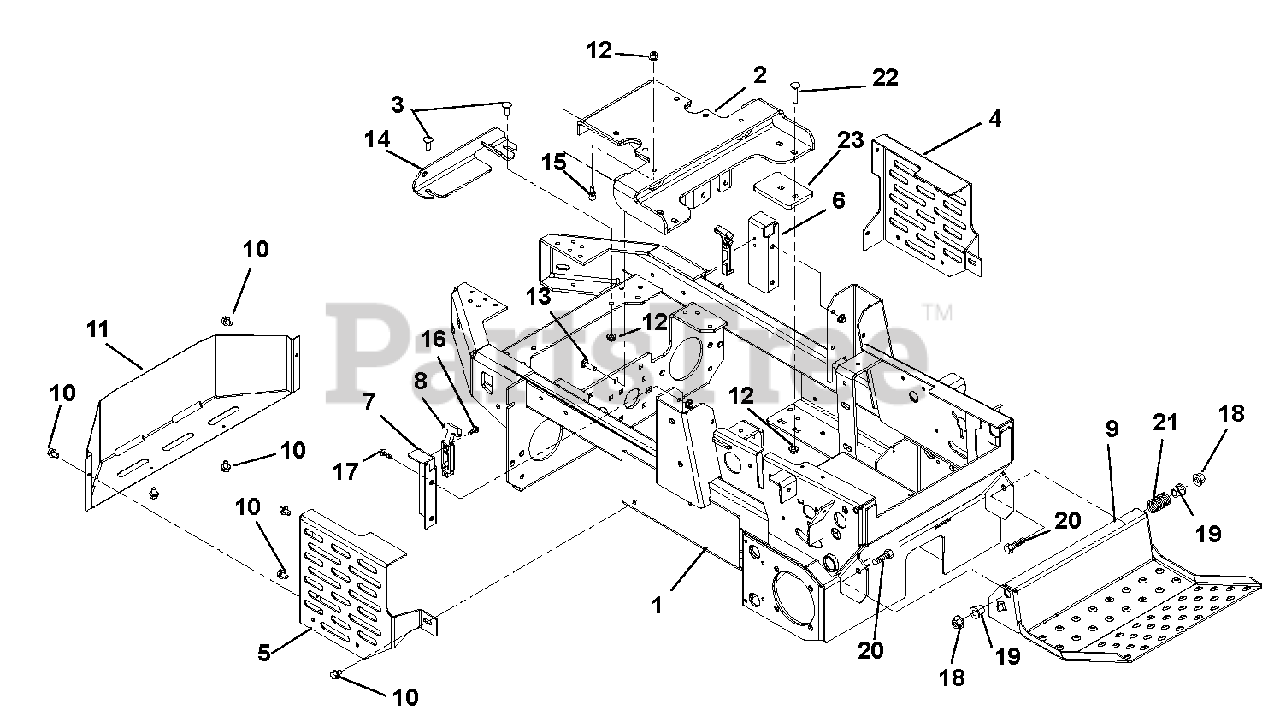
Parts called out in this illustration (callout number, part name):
1	Weldment, Frame
2	Plate, Kohler Engine Mounting
3	Bolt, Round Head Square Neck .38-16 x 1.00 Grade 5
4	Guard, Hose Fitting - Left Hand
5	Guard, Hose Fitting - Right Hand
6	Bracket, Left Hand Hood Mounting
7	Bracket, Right Hand Hood Mounting
8	Latch, Rubber
9	Weldment, Foot Plate
10	Screw, Tapping .38-16 x .75 Hex Washer Head
11	Guard, Pump Belt
12	Nut, .38-16 Nyloc Flange
13	Bolt, Round Head Square Neck .38-16 x 1.25 Grade 5
14	Weldment, Clutch Stop
15	Stud, Ball
16	Screw, Machine 10-24 x .50 Hex Washer Head
17	Screw, Tapping .38-16 x .50 Hex Washer Head Thread Rolling
18	Nut, Locking Top Flange .50-13
19	Bushing, Flange .515 x .746 x 1.290 x 1.000
20	Bolt, Hex .50-13 x 2.25 Grade 5
21	Spring, Compression .085 x .80 x 1.00 WLD36
22	Bolt, Round Head Square Neck .38-16 x 1.75 Grade 5
23	Strap, Engine Mounting Support
